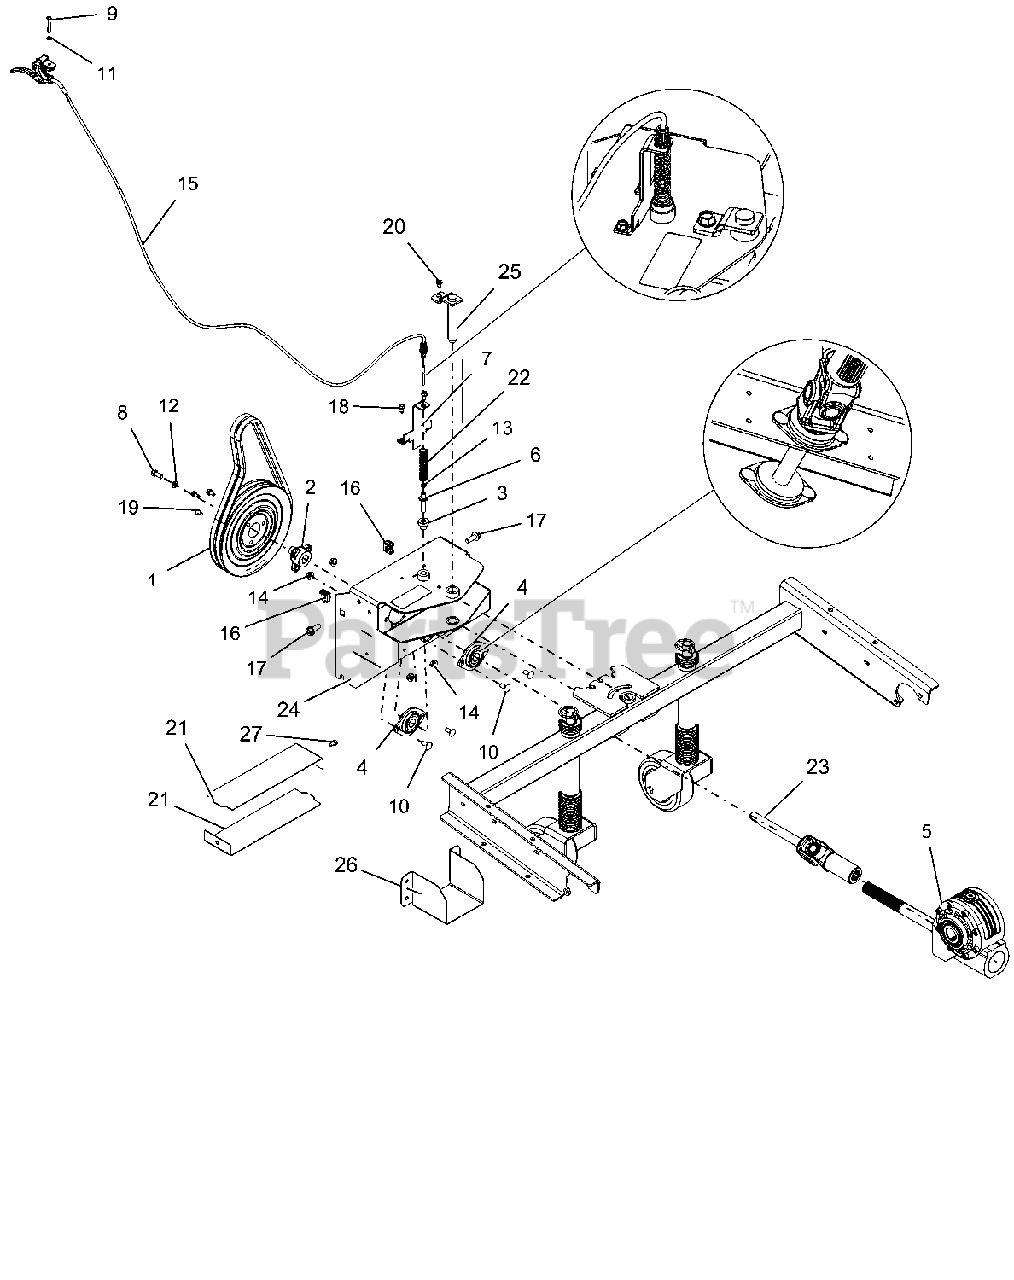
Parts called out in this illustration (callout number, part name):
1	PULLEY, SPIN FORM DUAL GROOVE
2	PULLEY HUB, BOLT-ON D-BORE .75
3	SPACER -FLANGED .390X.500X.781
4	BEARING, 2 BOLT FLANGE -.75 ID
5	GEARBOX, WORM - 8.25:1
6	PIN, ADJUSTABLE ANGLE BRUSH
7	BRKT, PIN HOLDER
8	BLT-HEX .31-24X.75 YWZC GR5
9	SCR-MCH .25-20X1.50 OVAL HD
10	@BLT-RDHDSQNK .31-18X.75 G5YZ
11	WSHR-LK-INT .250 TH TYA
12	WSHR-LK .312X.097 HVY YWZC
13	@NUT-HEX 10-24 YWZC
14	@NUT-LK-TOP-FLG .31-18 YWZC
15	CABLE, REMOTE BRUSH LOCK
16	NUT-RETNR .38-16 TINRMAN
17	BLT-SERHFWH .375-16X1.0 YWZC
18	SCR-TAP .25-20X.50 HWH TR YWZ
19	SCR-TAP .25-20X.50 HWH TR YWZ
20	SCR-TAP .25-20X.50 HWH TR YWZ
21	GUARD, BRUSH PTO
22	SPRING, COMPRESSION
23	DRIVELINE, SERIES 07 (U-JOINT)
24	ADAPTER, BRUSH
25	WLDMT, BRUSH PIN
26	GUARD, BRUSH U-JOINT
27	SCR-TAP .25-20X.50 HWH TR YWZ
